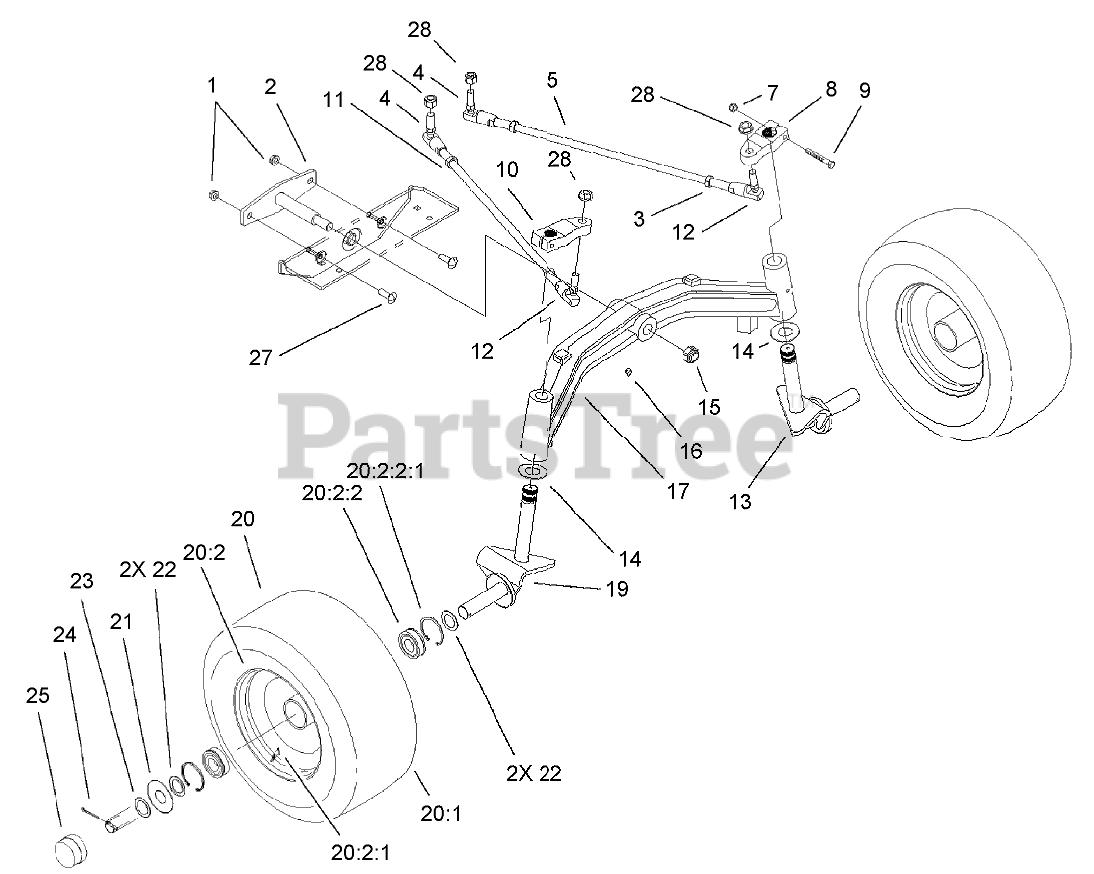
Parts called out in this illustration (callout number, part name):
1	NUT-LOCK, NI
2	Pin-Pivot
3	NUT-JAM
4	BALLJOINT-THREAD, LH
5	ROD-TIE
7	NUT-LOCK, NI
8	ARM-STEERING, LH
9	SCREW-HH
10	ARM-STEERING, RH
11	NUT-HJ (LH THREAD)
12	BALLJOINT-THREAD. RH
13	SPINDLE-LH
14	WASHER-THRUST
15	NUT-LOCK
16	FITTING-GREASE
17	AXLE-FRONT
19	SPINDLE-RH
20	WHEEL AND TIRE ASM
20:2	RIM ASM
20:2:1	VALVE
20:2:2	BEARING
20:2:2:1	Ring-Snap
21	WASHER-WHEEL
22	Washer
23	WASHER
24	PIN-COTTER
25	CAP-DUST
27	BOLT-CARR
28	NUT-LOCK
